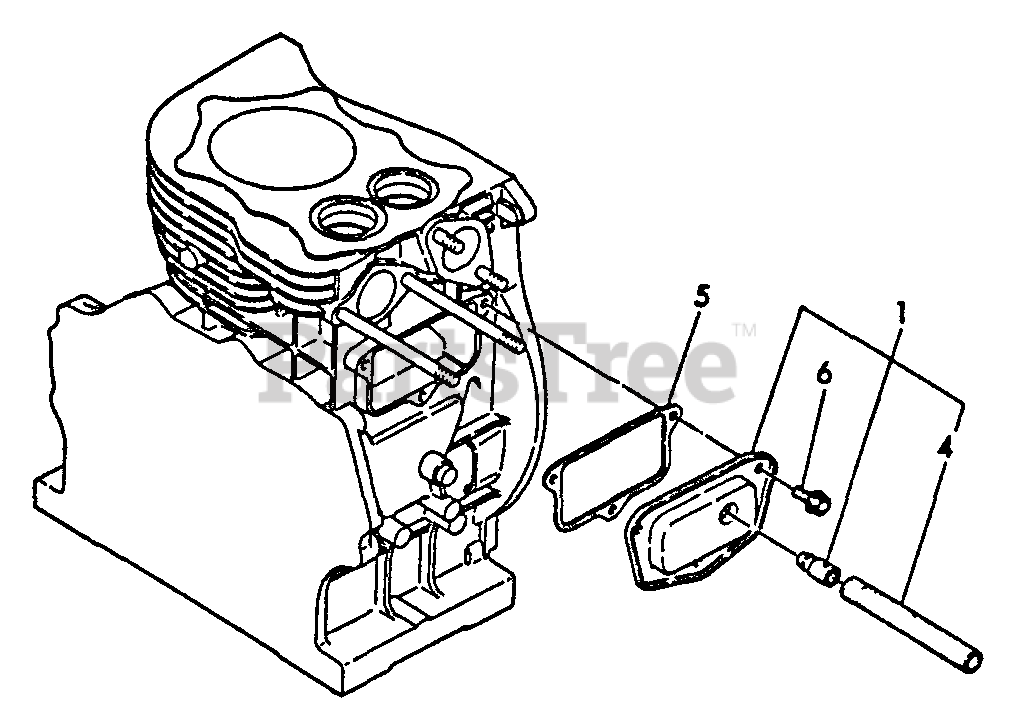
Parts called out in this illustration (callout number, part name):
1	VENT, FUEL TANK
4	PIPE - BREATHER
5	GASKET, BREATHER
6	BOLT - 6X8 -- PLATED
